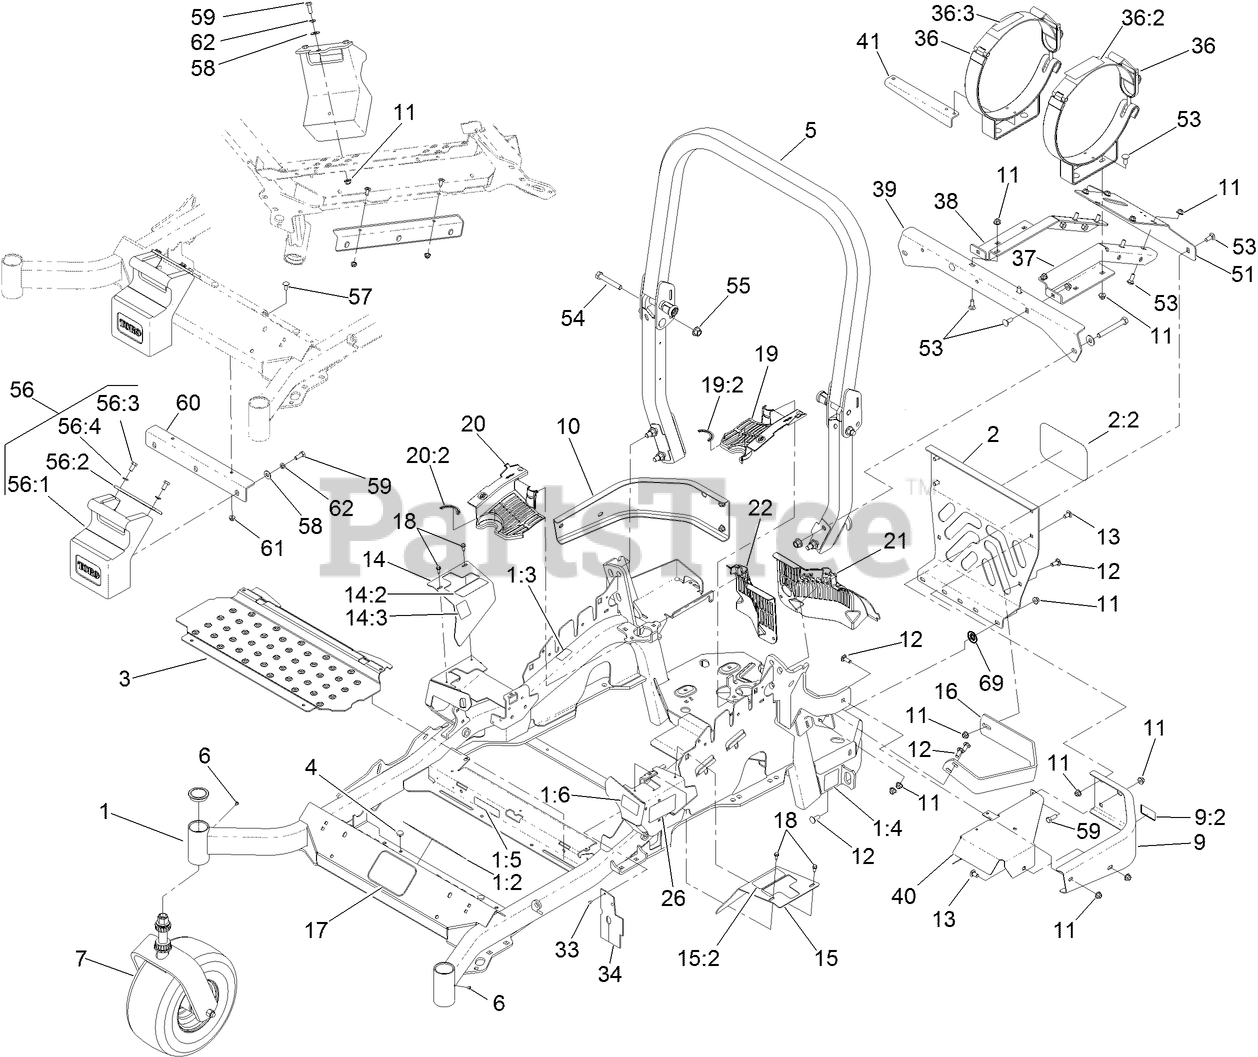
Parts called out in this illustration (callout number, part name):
1	MAINFRAME ASM
1:2	DECAL-SLOPE
1:3	DECAL-CAUTION
1:4	DECAL-BELT DRIVE
1:5	DECAL-SPARK ARRESTER
1:6	DECAL-FUEL FILL
2	REAR GUARD ASM
2:2	DECAL
3	FLOORPAN
4	BUMPER
5	ROPS ASM
7	Caster Wheel ASM
9	LH BUMPER ASM
9:2	DECAL-CAUTION
10	BUMPER-RH
11	NUT-HF, NI
12	SCREW-CARR
13	SCREW-CARR
14	RH MOTION CONTROL COVER ASM
14:2	DECAL-MOTION CONTROL
14:3	DECAL-PARK BRAKE
15	LH MOTION CONTROL COVER ASM
15:2	DECAL-MOTION CONTROL
16	GUARD-MUFFLER
17	DECAL
18	SCREW-HWH
19	LH HYDRO GUARD ASM
19:2	DECAL-HYDRO OIL
20	RH HYDRO GUARD ASM
20:2	DECAL-HYDRO OIL
21	GUARD-HYDRO, REAR (LH)
22	GUARD-HYDRO, REAR (RH)
33	RIVET-POP
34	DEFLECTOR-AIR FLOW
36	TANK BRACKET ASM (SET)
36:2	DECAL-LPG WARNING
36:3	DECAL-LPG 43.5LB TANK
37	LH LPG FRAME ASM
38	RH LPG FRAME ASM
39	SUPPORT-LPG FRAME, FRONT
40	PANEL-LPG, AC
41	PLATE-INDEX, LPG TANK
51	SUPPORT-REAR FRAME, LPG
53	BOLT-CARR
54	SCREW-HH
55	NUT-LOCK
56	WEIGHT ASM
56:1	WEIGHT-43 LB
56:2	TAB-SUPPORT, WEIGHT
56:3	SCREW-HH
56:4	WASHER-LOCK
57	SCREW-CARR
58	WASHER-FLAT
59	SCREW-HH
60	BRACKET-MOUNT, WEIGHT
61	NUT-HF, NI
62	WASHER-LOCK
69	NUT-PUSH
